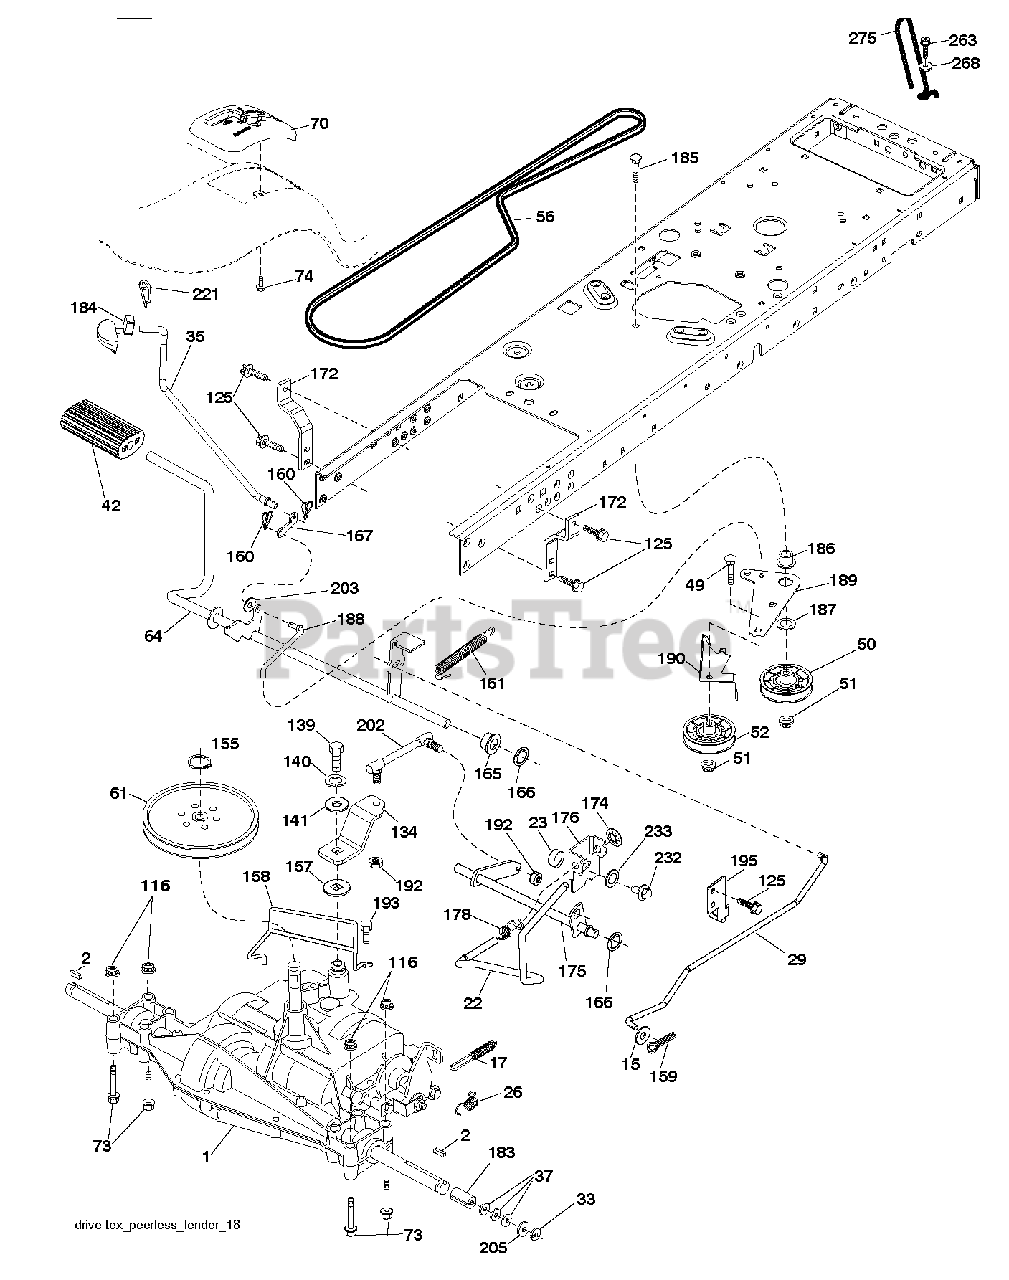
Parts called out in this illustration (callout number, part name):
2	SQUARE KEY
17	SPRING.BRAKE.PEERLESS.TEX
22	ROD.SHIFT.FENDER.TLT.2006
23	KNOB.DUCKHEAD.1/2
26	SPRING.BRAKE.RTN.GR.DR
29	ROD.BRAKE.PEERLESS
33	E-RING LT
35	ROD, BRAKE, PARK
42	PEDAL COVER T
49	BOLT
50	IDLER.FLAT.910.OFFSET
51	NUT LOCK FLG 3/8-16 UNC
52	IDLER.V-GROOVE.910.OFFSET
56	V-BELT.TRACTOR.DRIVE.P
61	PULLEY TRANS
64	SHAFT.ASM.PEDAL.BRAKE.
70	CONSOLE.SHIFT.
73	BOLT HEX 5/16-18 GR 5
74	SCREW.HI-LO.CONSOLE
116	NUT LOCK HEX FLANGE 5/16-18
125	SCREW
134	ARM SHIFT
139	BOLT 1/4-28X3/4
140	LOCKWASHER
141	WASHER LT
155	RETAINING RING LT
157	WASH-SHFT PLT LT
158	KEEPER.PMS.18/20.D4365
159	COTTER PIN
160	RETAINER CLIP
161	SPRING, RETURN LT
165	BUSHING.SHAFT.BRAKE.HAND
166	NUT.PUSH.625
167	LATCH.BRAKE.SPRING
172	STRAP.TRQ.LH.GEAR.DRIV
174	NUT.PUSH.500.2006
175	SHAFT ASM SHIFT
176	ARM.CLEVIS.ROD.SHIFT
178	SPRING.SHIFT.GT2006
183	SPACER AXLE
184	HANDLE PARKING BRAKE
186	SPACER.RETAINER
187	WASHER 12/32X2X10GA
188	LINK.CLUTCH.GROUND.DRIVE
189	BELLCRANK.GROUND.DRIVE.TEX.
190	KEEPER.BELLCRANK.DRIVE
192	NUT LOCK CENTER 1/4 -28 FNTHD
193	SCREW 5/16"
195	BRKT.ROD.BRAKE.PEERLES
202	LINK.SHIFT.PMST.18"
203	WASHER
221	RETAINER.SPRING.CLIP.H
232	BOLT FIN HEX 7/16-14 X 1
233	WASHER SERRATED
263	SCREW, 3/8-16X3/4
268	WASHER
